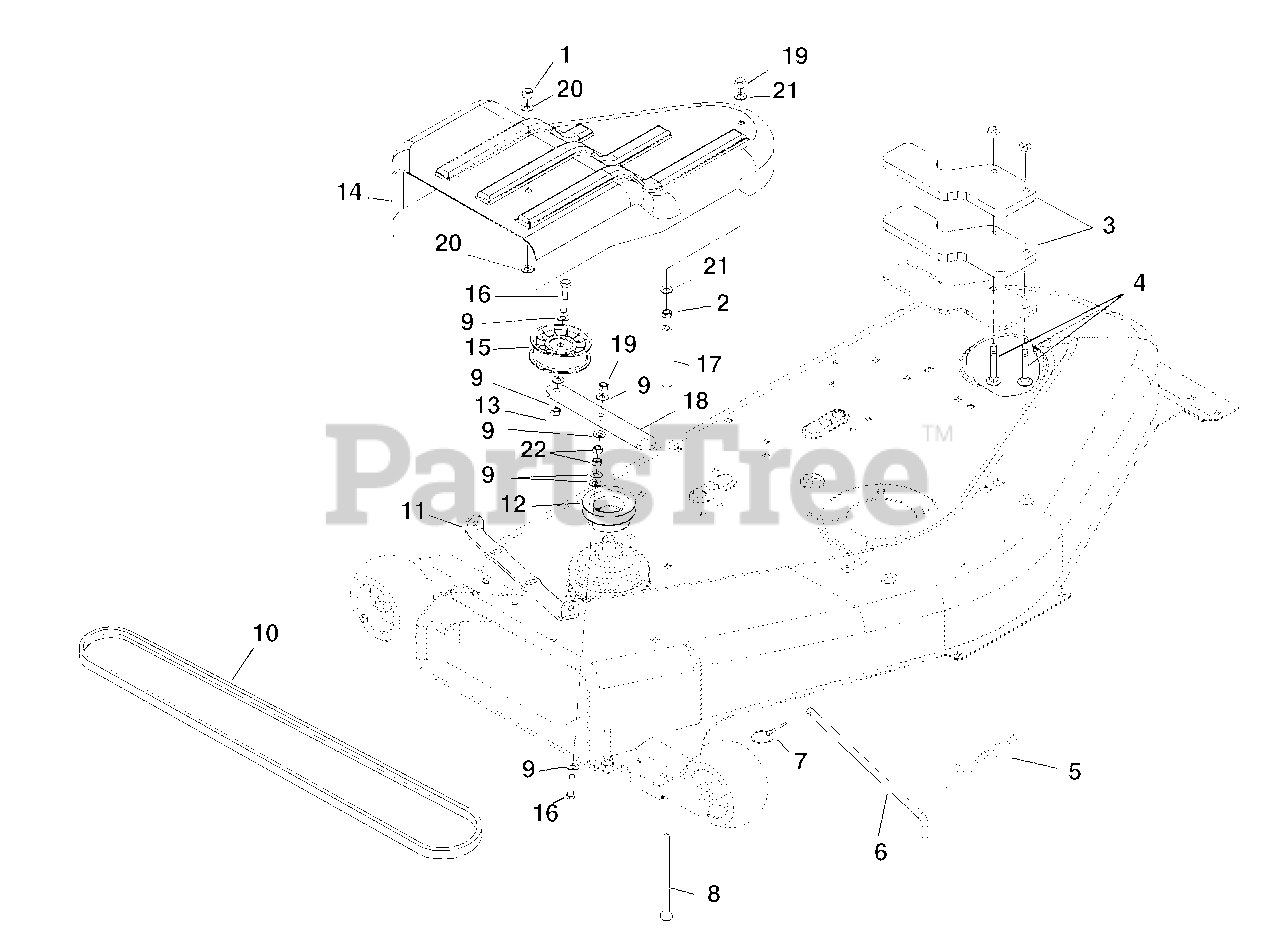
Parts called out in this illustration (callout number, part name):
1	Nut-Lock-Nylon .250-20
2	Nut-Locking-Center .312-18
3	Counterweight
4	Bolt-Round Head Square Neck .31-18 x 1.75 Grade 5
5	Spring-Tension .069 x .62 x 3.50
6	Rod-Mounting
7	Pin-Klik 1.000 x .188 x 1.25
8	Bolt-Hex .31-18 x 5.50 Grade 5
9	Washer-Flat-Steel .344 x .688 x .065
10	V-Belt A-Section 25.95 x .516
11	Bracket-Chute Pivot
12	Pulley-Driver 3.00"
13	Nut-Locking-Flange .31-18
14	Cover, Belt
15	Idler-Flat 3.00 x .38
16	Bolt-Hex .31-18X1.75 Grade 5
17	Spacer-.334 I.D. x 4.63
18	Bracket-Tension Arm
19	Nut-Lock-Nylon .31-18
20	Washer-Flat-Steel .281 x 1.00 x .048
21	Washer-Flat-Steel .344 x 1.375 x 0.75
22	Nut-Jam .31-18
